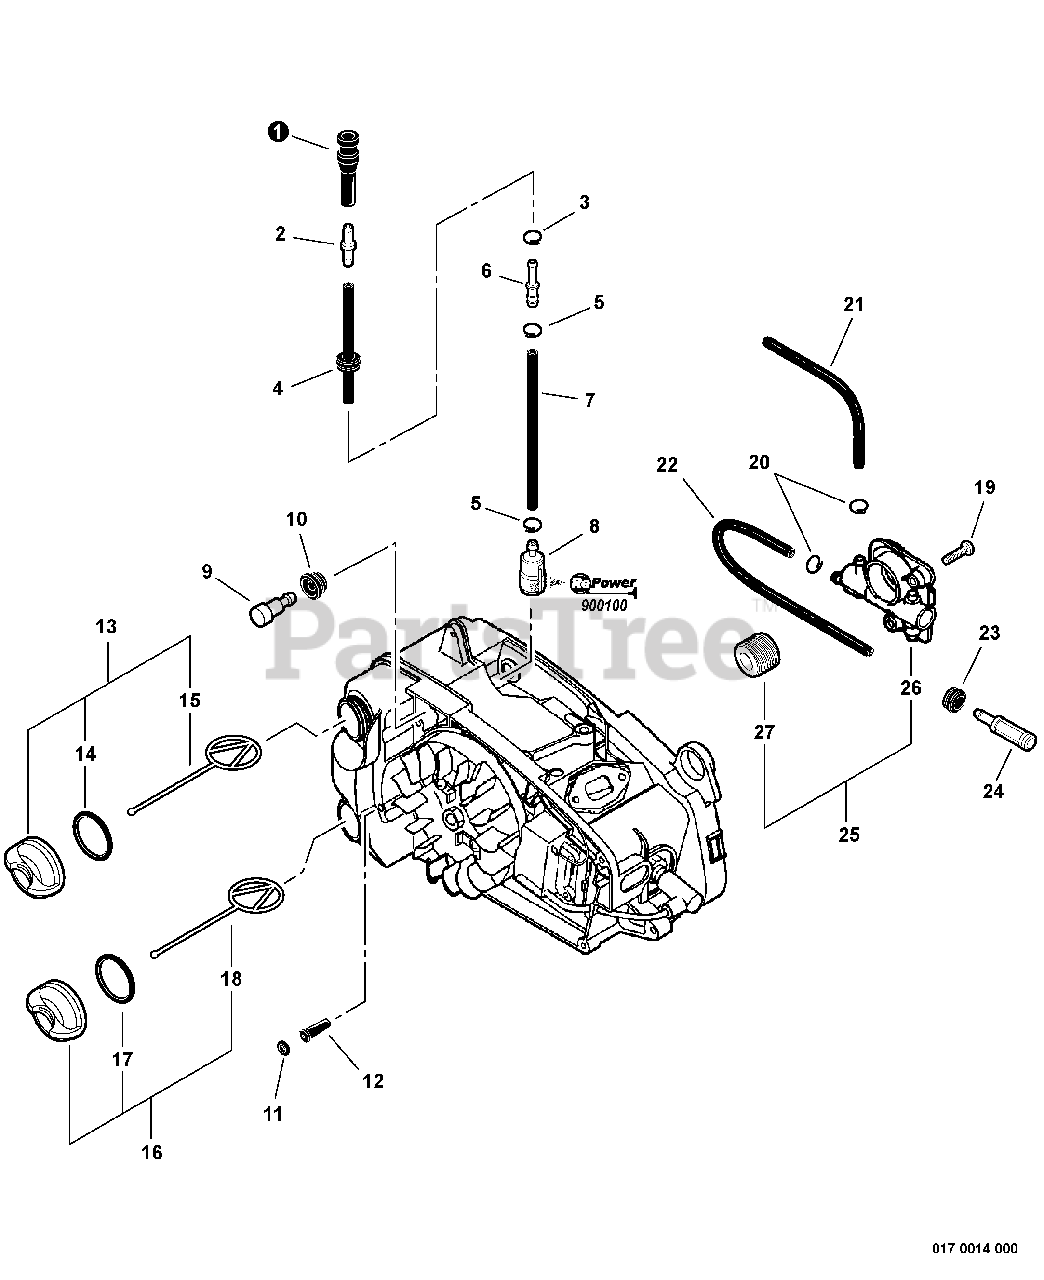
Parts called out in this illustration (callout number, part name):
1	PIPE - FUEL
2	CONNECTOR, PIPE
3	CLIP - 5
4	FUEL PIPE ASSY
5	CLIP - 6
6	CONNECTOR, PIPE
7	PIPE - 3X5X95 -- BLACK
8	FILTER, FUEL
9	VENT, FUEL TANK
10	GROMMET
11	O-RING - 4
12	VENT, TANK
13	CAP ASSY - ORANGE
14	O-RING - 18
15	CONNECTOR, CAP
16	CAP ASSY - BLACK
17	O-RING - 18
18	CONNECTOR, CAP
19	SCREW - 4X12
20	CLIP - 6.5
21	PIPE - 3X6X90 -- BLACK
22	PIPE - 3X5X195 -- BLACK
23	GROMMET
24	FILTER, OIL
25	AUTO-OILER ASSY
26	AUTO-OILER ASSY
27	GEAR - WORM
28	RePower TUNE-UP KIT
